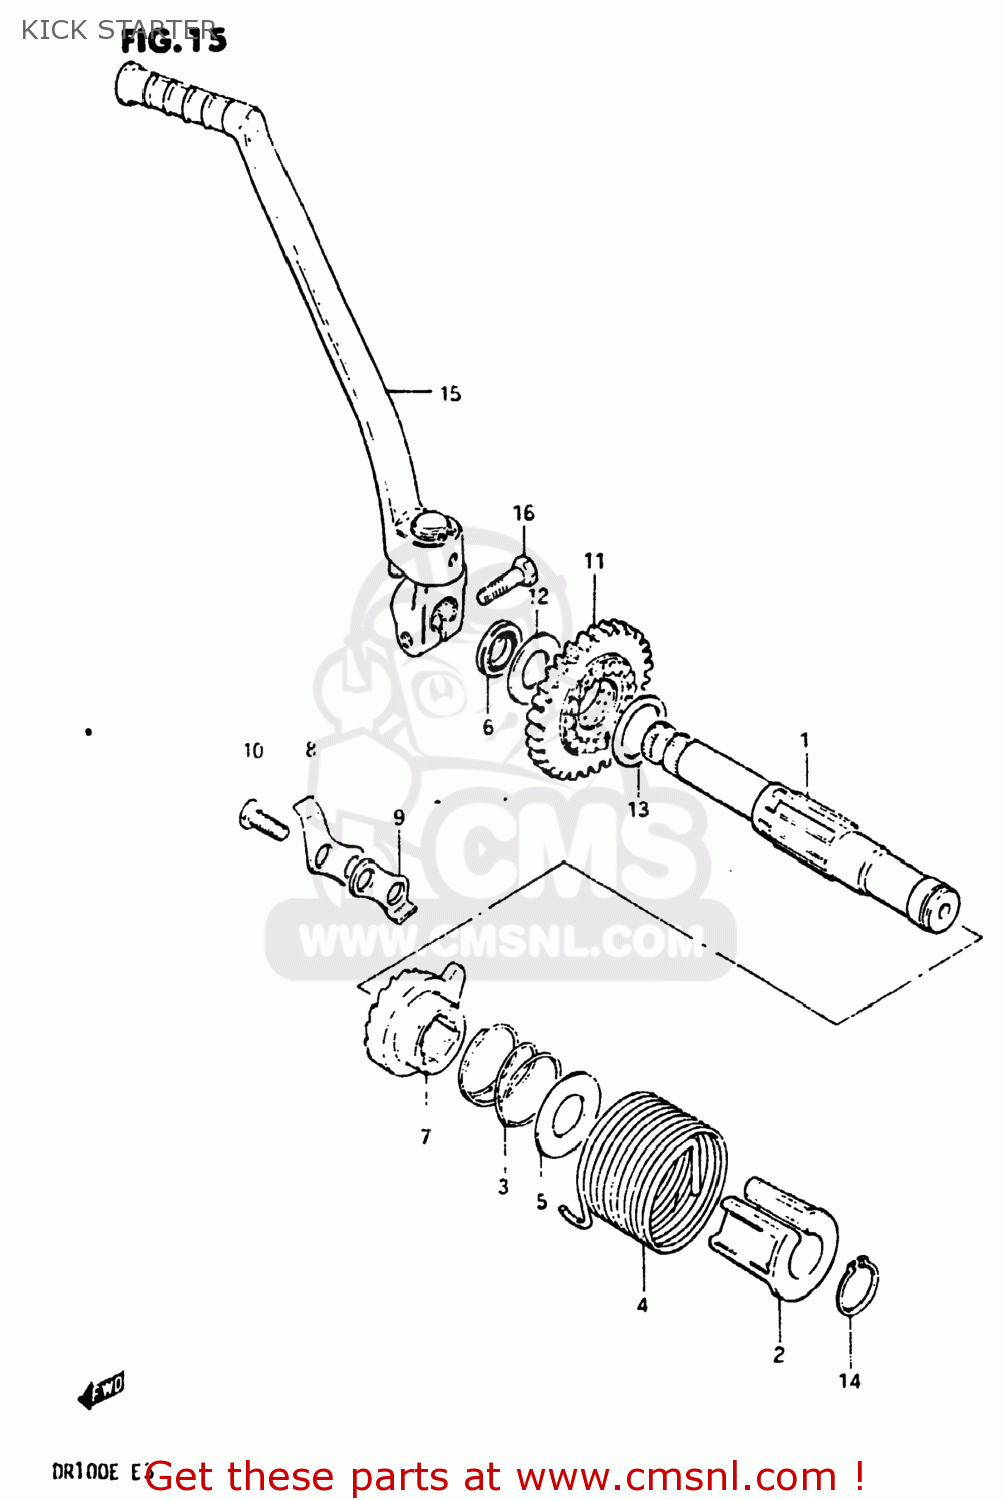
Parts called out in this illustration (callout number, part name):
1	SHAFT,KICK STARTER
2	GUIDE,KICK STARTER SFT SPRING
3	SPRING
4	SPRING
5	WASHER
6	SEAL,OIL(16X24X5)
7	STARTER,KICK
8	GUIDE,KICK STARTER
9	STOPPER,KICK STARTER
10	BOLT
11	GEAR,KICK STARTER DRIVE
12	WASHER(16X30X1)
13	WASHER
14	CIRCLIP
15	LEVER ASSEMBLY,KICK STARTER
16	BOLT 8X25
